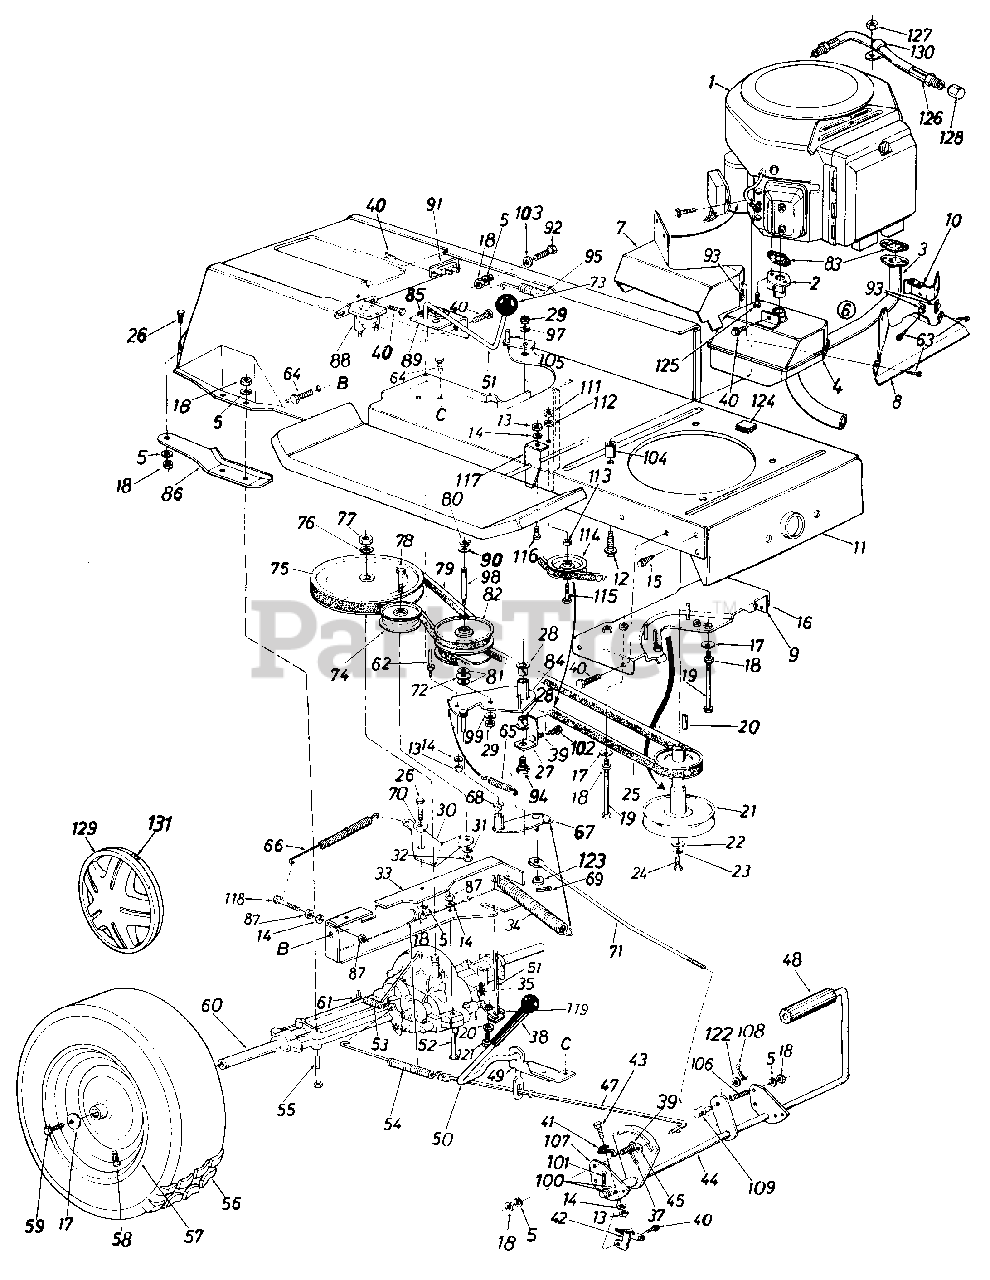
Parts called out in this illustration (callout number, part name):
1	Engine
2	Inlet Tube Ass'y.
3	Formed Tube Ass'y.
4	Exhaust Muffler Sub Ass'y.
5	L-Wash. 5/16" I.D.
6	Muffler Ass'y. Comp.
7	Muffler Heat Shield
8	Front Heat Shield
9	Brake Cable Brk't.
10	Front Heat Shield Ext.
11	Lower Frame Ass'y.
12	Hex Wash. Hd. TT-Tap Scr. 3/8-16 Thd.
13	Hex Nut 1/4-20 Thd.
14	L-Wash 1/4" I.D.*
15	Hex Wash. Hd. AB-Tap Scr. 5/16" x.75" Lg.
16	Belt Guard Brkt. Ass'y.
17	Bell-Wash. .345" I.D. x .88"
18	Hex Nut 5/16-18 Thd.
19	Hex Bolt 5/16-18 x 4.00"
20	Sq.Key 1/4"x 1/4"x 2.00"
21	Engine Pulley
22	Fl-Wash. 7/16" I.D. x 1.25"
23	L-Wash. 7/16" I.D.
24	Hex Bolt 7/16-20 x 1.50" Lg.
25	Variable-Speed Belt
26	Hex Bolt 5/16-18 x .75" Lg.
27	Bearing Shaft Bracket Ass'y.
28	Flanged Nyliner Brg. 518" I.D. x .88" Lg.
29	Hex Nut 3/8-24 Thd.*
30	Idler Bracket
31	L-Wash. 3/8" I.D.
32	Hex Nut 3/8-24 Thd.
35	Inter. Cotter Pin
37	Cotter Pin 3/32" Dia. x .75"
38	Grip-Black
39	Truss Mach. Scr. 5/16-18 x .75" Lg.
40	Hex Wash. Hd. Self-Tap Scr. 1/4-20 x .50" Lg.
41	Switch Actuator
42	Safety Switch
43	Hex Bolt 1/4-20 x 1.0" Lg.
44	Clutch & Brake Pedal Ass'y.
45	Fl-Wash.
47	Brake Rod 20.9" Lg.
48	Foot Pad
49	Brake Lever Bracket
50	Hill Holder Brake Handle
51	Shift Lever Ass'y.
52	Hex Bolt 1/4-28 x 1.75" Lg.
53	Ext. Spring x 2.5" Lg.
54	Ext. Spring x 7.08" Lg.
55	Hex Bolt 5/16-18 x 2.75"
58	Air Valve
59	Hex Bolt 5/16-24 x .75" Lg.
60	Transaxle Complete-R.H.
61	Brake Return Spring Anchor
62	Belt Guard Pin 1/4-20 Thd.
63	Hex AB-Tap Scr. #10 x .5" Lg.
64	Hex Wash. TT-Tap Scr. 5/16 x .62" Lg.
65	Ext. Spring
66	Ext. Spring .62" O.D. x 6.12"
68	Flanged Bearing
69	Cotter Pin 3/32" Dia.
70	Shoulder Spacer .500" Dia. x.27" Lg.
71	Speed Control Link
72	Truss Bearing .56" Dia. x 1 .25"
73	Ball Knob
74	Fl-Idler Pulley 3.25" x .75"
75	1/2" "V"-Pulley 8.0" O.D. x.501" I.D.
76	L-Wash. 1/2" I.D.
77	Hex Jam Nut 1/2-20 Thd.
78	Hex Bolt 3/8-24 x .75" Lg.*
79	Variable-Speed Belt
80	Snap Ring .56" Dia.
81	Fl-Wash.
82	Variable Speed Pulley Ass'y. 5" O.D.
83	Gasket
86	Axle Support Brkt.-R.H.
87	Hex Nut 1/4-28 Thd.
88	Solenoid
89	Shift Lever Bracket
90	Teflon Washer
91	Circuit Breaker
92	Hex Bolt 5/16-18 x 1.50" Lg.
93	Speed Nut #10-24 Thd.
94	Shld. Bolt 3/8-24 x 3.12" Lg.
95	Ext. Spring .99" O.D. x 11.0"
97	Bell-Wash. .38" I.D. x .88"
98	Shaft .56" Dia. x 3.875" Lg.
99	Bell-Wash. .39" I.D. x 1.12"
100	Fl-Wash.
101	Cotter Pin 3/32" Dia. x .75"
102	Hex Wash. Hd. Scr. 5/16-18 x.62" Lg.
103	Fl-Wash. .34" I.D. x 1.12"
104	Spacer 5/16" I.D.
105	Belt Guard
106	Hex Bolt 5/16-18 x .75" Lg.
107	Pedal Bracket
108	Cotter Pin 3/32 x .75"
109	Ferrule
111	Hex Nut 3/8-16 Thd.
112	L-Wash. 3/8" I.D.
113	Fl-Wash. .390" I.D. x 1.12"
114	Fl-Idler w/Flanges 2.750
115	Hex Bolt 3/8-16 x 2.00" Lg.
116	Hex Bolt 1/4-20 x .62" Lg.
117	Spring Hanger Bracket
118	Hex Bolt 1/4-28 x 1.25" Lg.
119	Shift Lever Link Ass'y.
120	Bell-Wash. .265" I.D. x .75"
121	Hex Bolt 1/4-28 x .62" Lg.
122	Fl-Wash. .385" I.D. x .62"
123	Fl-Wash. .34" I.D. x .68" O.D.
124	Foam Strip
125	Hex Bolt w/Washer
126	Oil Drain
127	Hex Jam Nut 3/8-16 Thd.
128	Cap Oil Drain
129	Hub Cap
130	Clamp
131	Mounting Clip
